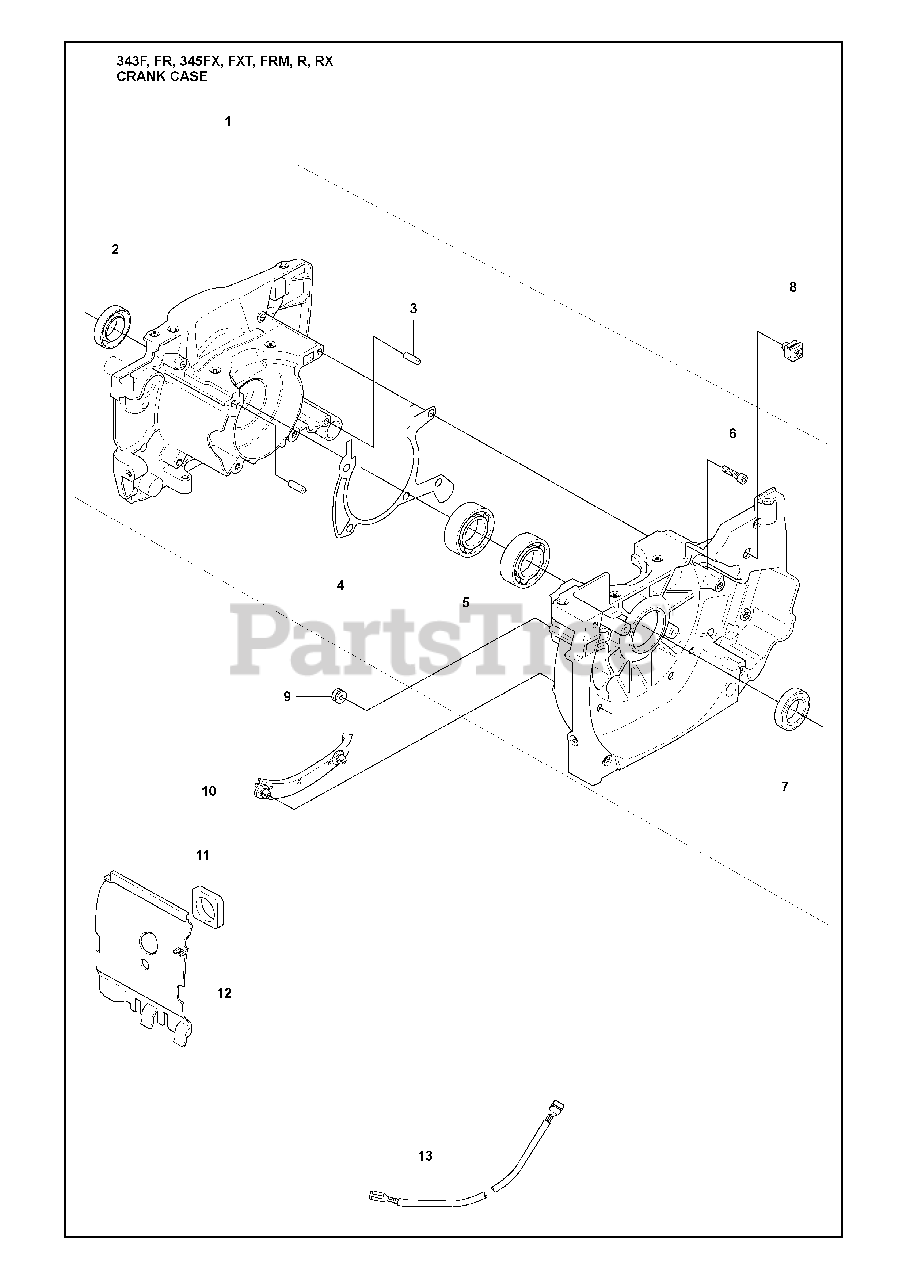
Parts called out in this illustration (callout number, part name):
2	SEALING RING
3	PIN 5X14
5	BALL BEARING-6202-C3 SKF
6	SCREW MC6S 5X20
8	Cable Socket
9	FUEL TANK BUSHING
11	SEAL
12	AIR CONDUCTOR
13	SHORTING LEAD
